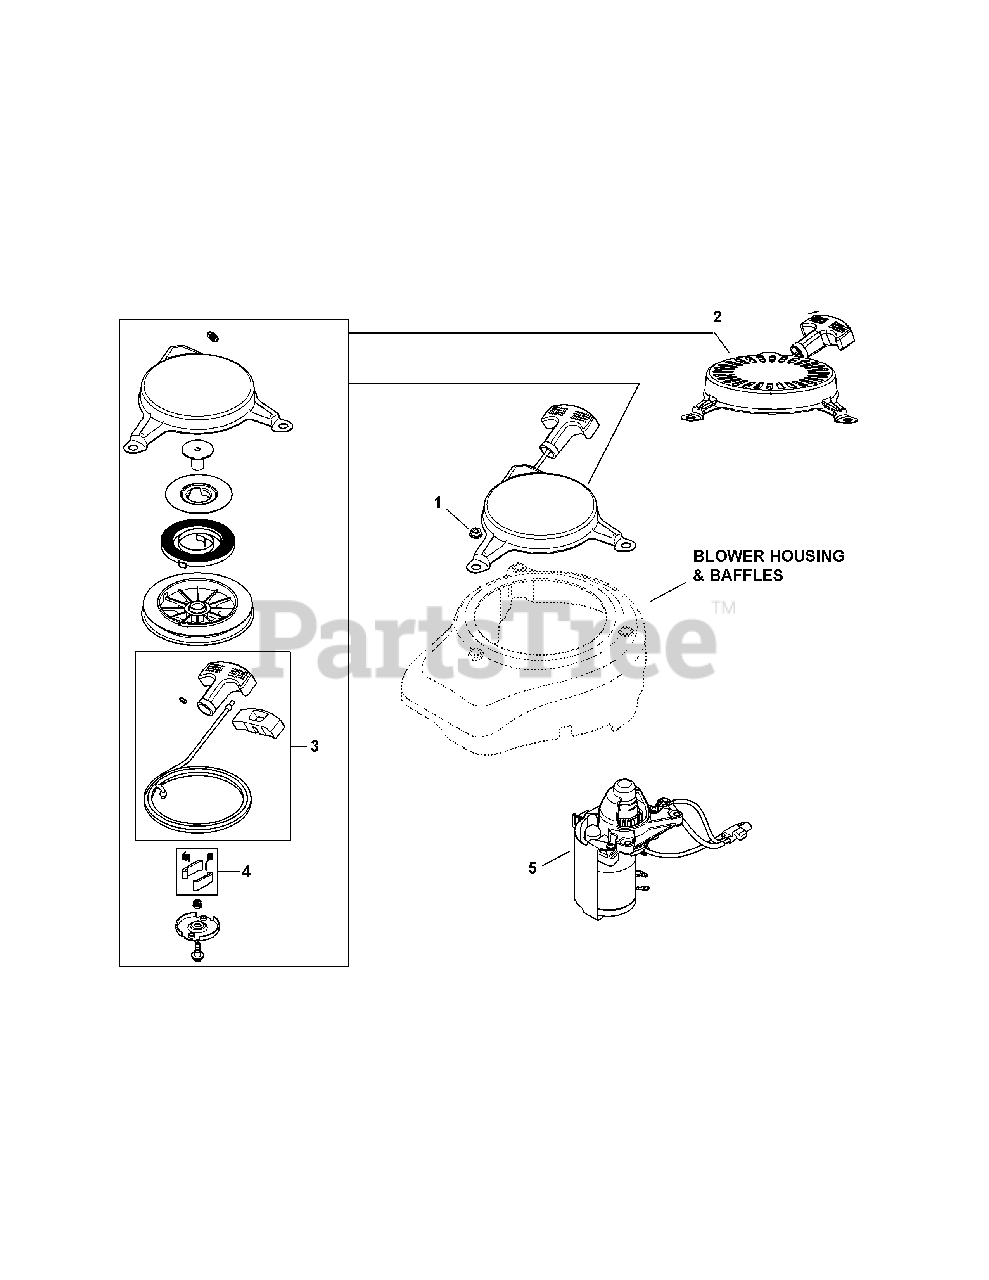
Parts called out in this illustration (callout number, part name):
1	Nut, Hex Flange, M6
2	Starter Assembly, Retractable
3	Recoil Starter Rope
4	Kit, Pawl Repair
5	Electric Starter w/ BBC
